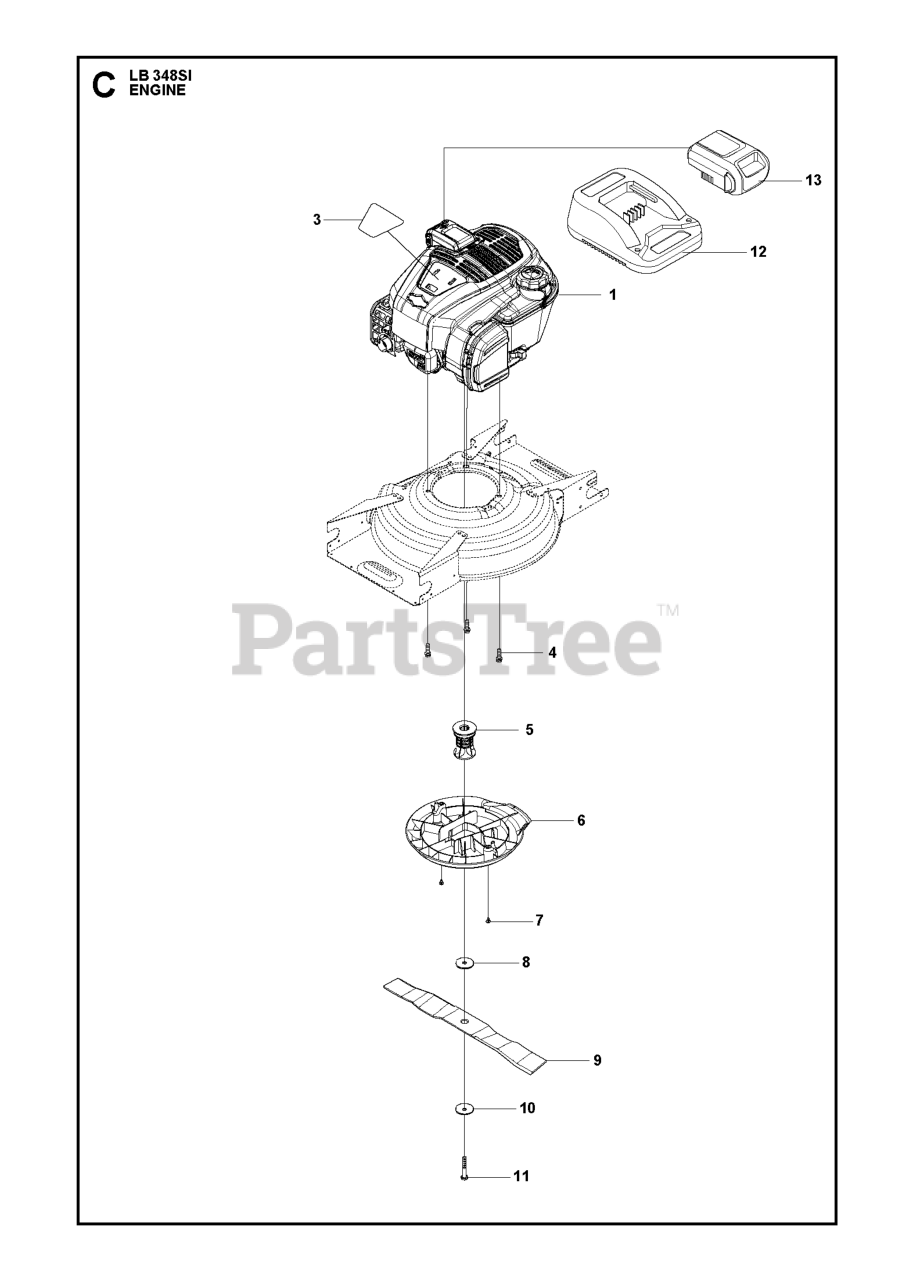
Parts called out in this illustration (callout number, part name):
4	BOLT 3/8-16X1-1/8
6	BELT COVER A009-2
7	SCREW ITXPANTT M5X10 ZPB (A00
